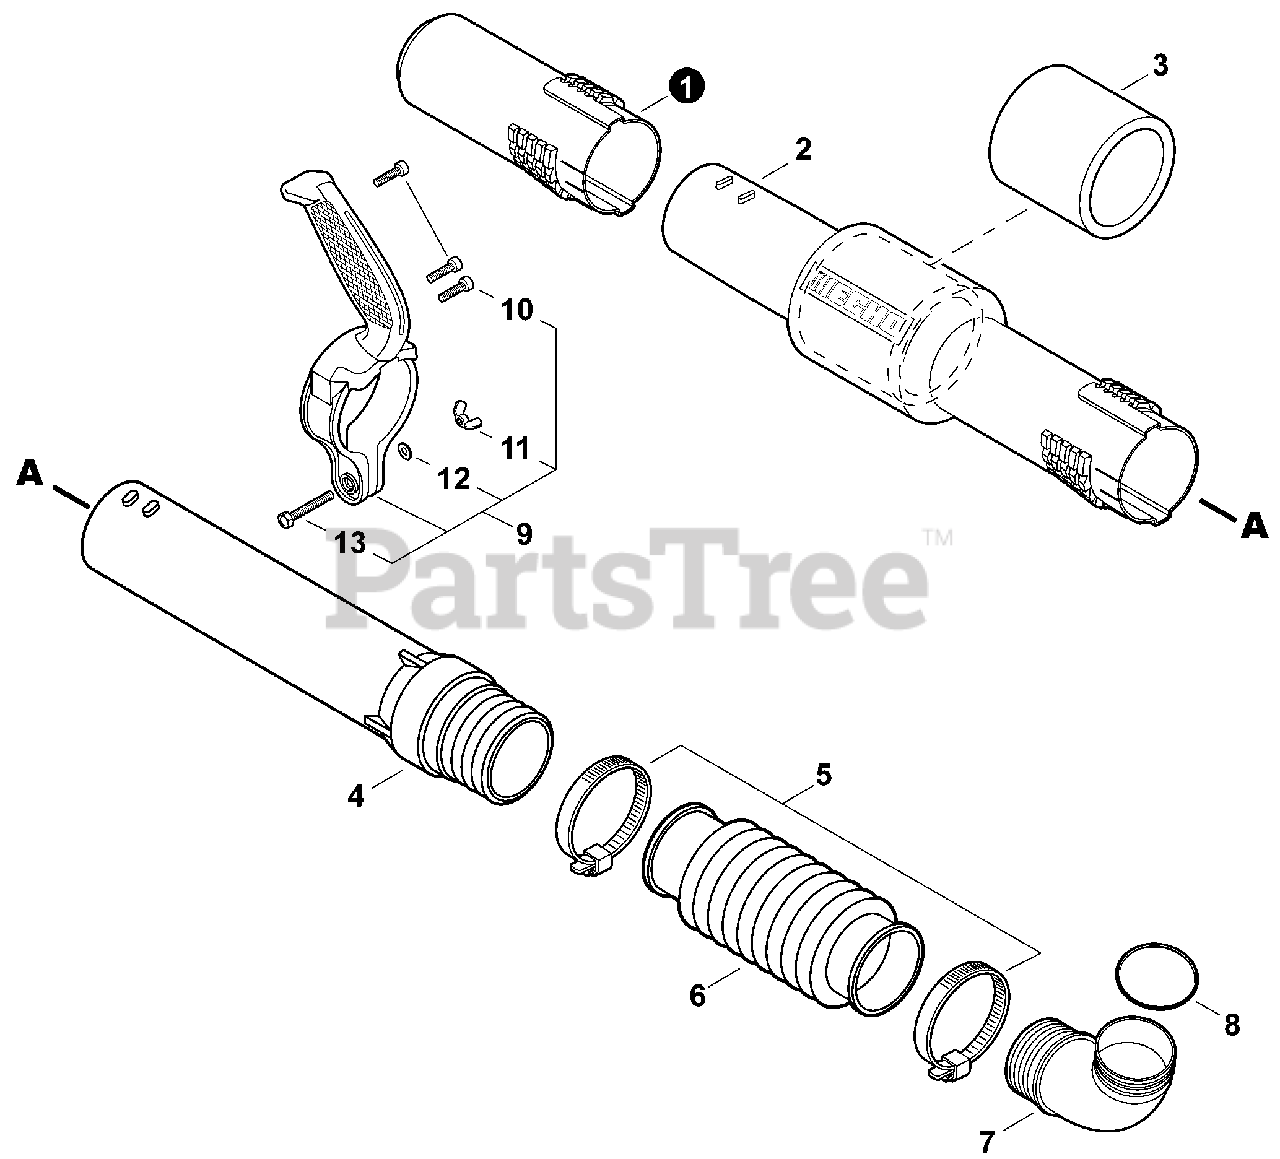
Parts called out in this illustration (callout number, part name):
1	TUBE, BLOWER - NOZZLE
2	TUBE, BLOWER - STRAIGHT
3	PAD, FOAM
4	TUBE, BLOWER - SWIVEL
5	CLAMP - BAND
6	TUBE, BLOWER - FLEXIBLE
7	TUBE, BLOWER - ELBOW
9	HANDLE KIT - BLOWER TUBE
10	BOLT, TORX 4×16
11	NUT, WING 6
12	WASHER 6.5×11.5×0.8
13	BOLT 6×25
